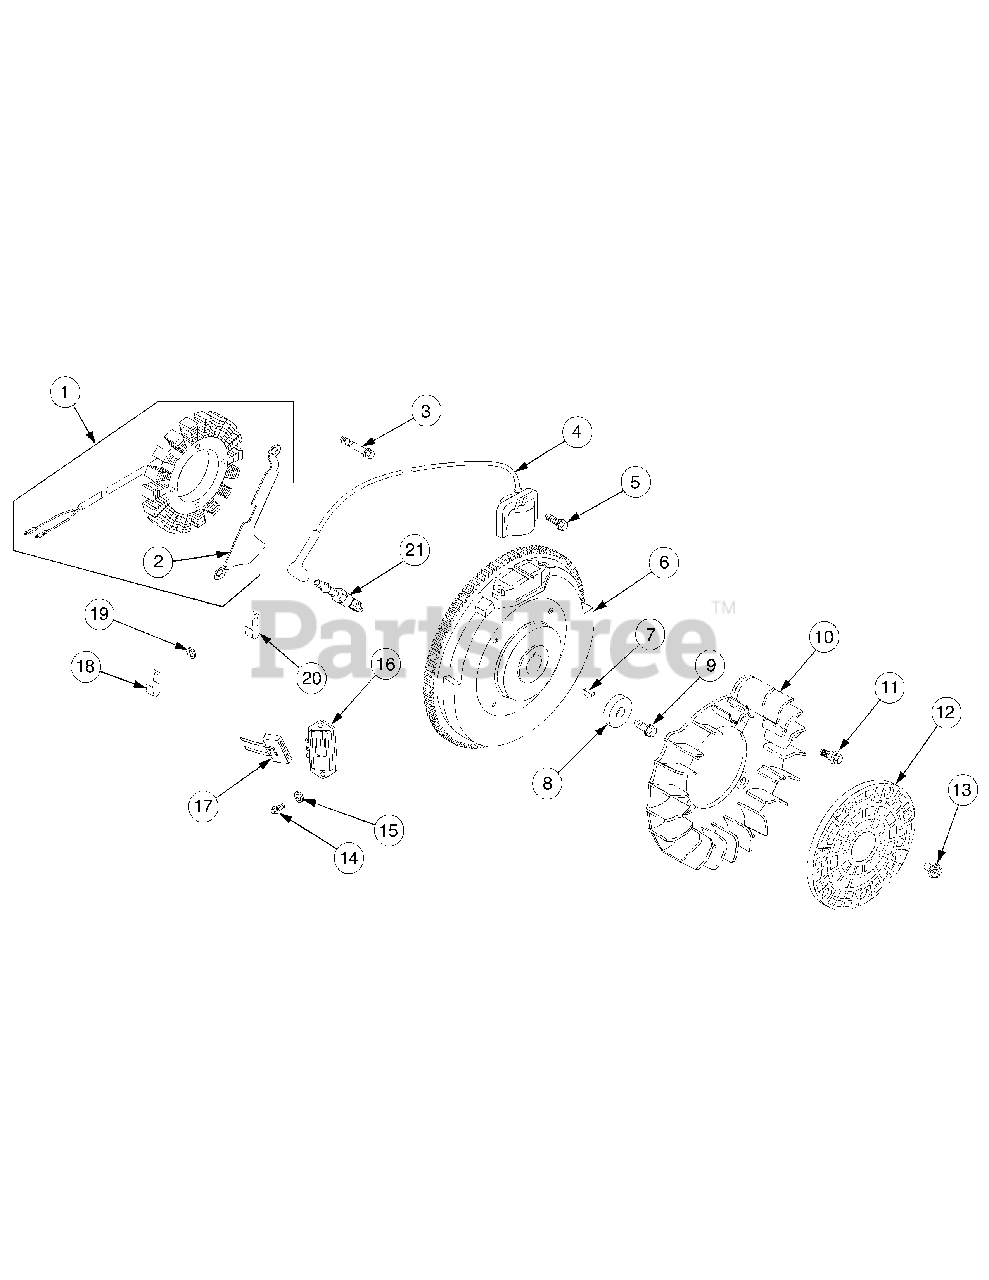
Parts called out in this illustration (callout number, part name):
1	Stator Kit, 15 Amp (Incl. Ref #2)
2	Bracket, Stator Wire
3	Screw, Stator Mtg. M5 x .8 x 25
4	Module, Ignition
5	Screw, Module M5 x .8 x 20
6	Flywheel Assembly
8	Washer, Flywheel Mtg. Screw
9	Screw, Flywheel Mtg, M10x1.5 x 46
10	Fan
11	Bolt, Shoulder
12	Screen, Grass
14	Screw Phillips Hd., #11-16 x .875
15	Washer, Plain
16	Regulator - Rectifier
17	Connector, Regulator-Rectifier
18	Clip, Cable
19	Washer, Plain 1/4"
21	Spark Plug
